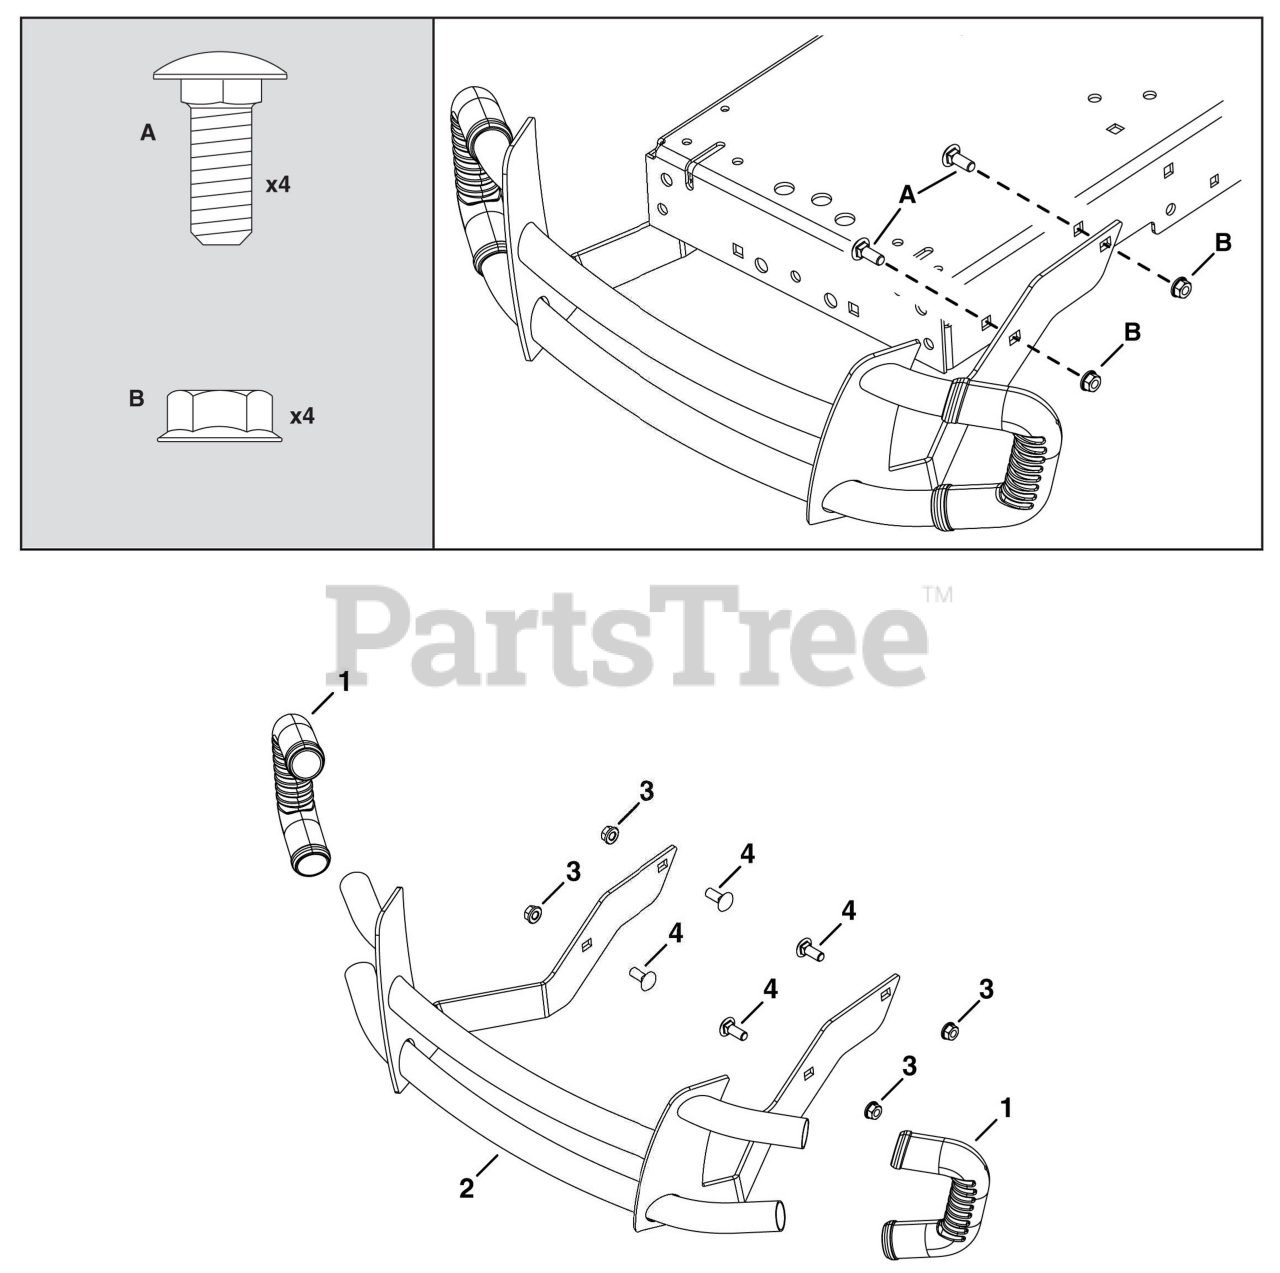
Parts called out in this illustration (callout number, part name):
2	Bumper Assembly
3	Carriage Bolt, 3/8-16 x 1"
4	Whizlock Nut, 3/8-16
